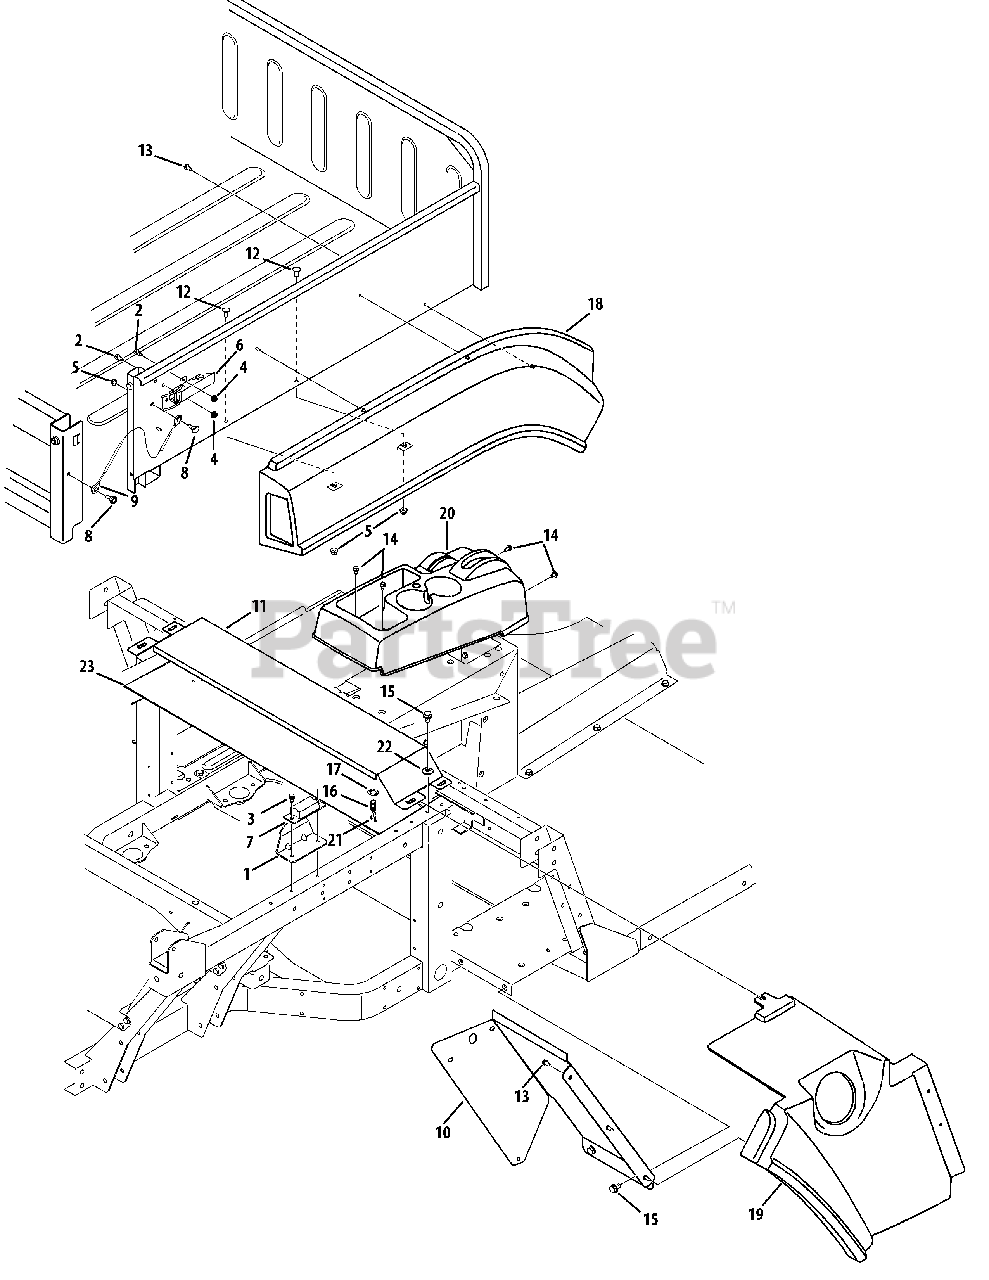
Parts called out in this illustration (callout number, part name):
2	Scr, mach, #10-24, 0.500, trusphi
3	Scr, tt, 1/4-20x.625, hxindwsh
4	Nut, hexlk, #10-24, gr2, nylon
5	Nut, flglk, 1/4-20, grf, nylon
6	Latch, draw, over Center
7	Bmpr, suspn, extn
8	Scr, shldr, .375x.280, 1/4-20
9	Cbl, lanyard
12	Scr, Crg, 1/4-20, .62, Gr2
13	Scr, #12-16, .50, Hxindwsh
14	Scr, Tt, 1/4-20, 0.500
15	Scr, Tt, 5/16-18, 0.500
16	Spr, Comprs, .40 OD X .040 Dia.
17	Latch, Pnl, 1/4 Turn
18	Fdr, Rh Rr
18	Fdr, Rh Rr, Camo
19	Fdr, Lwr Rh Rr
19	Fdr, Lwr Rh Rr Camo
20	Cnsol, Seat
22	Washer, Bell, .340 x .872 x .060
23	Insl., CVR, UV
